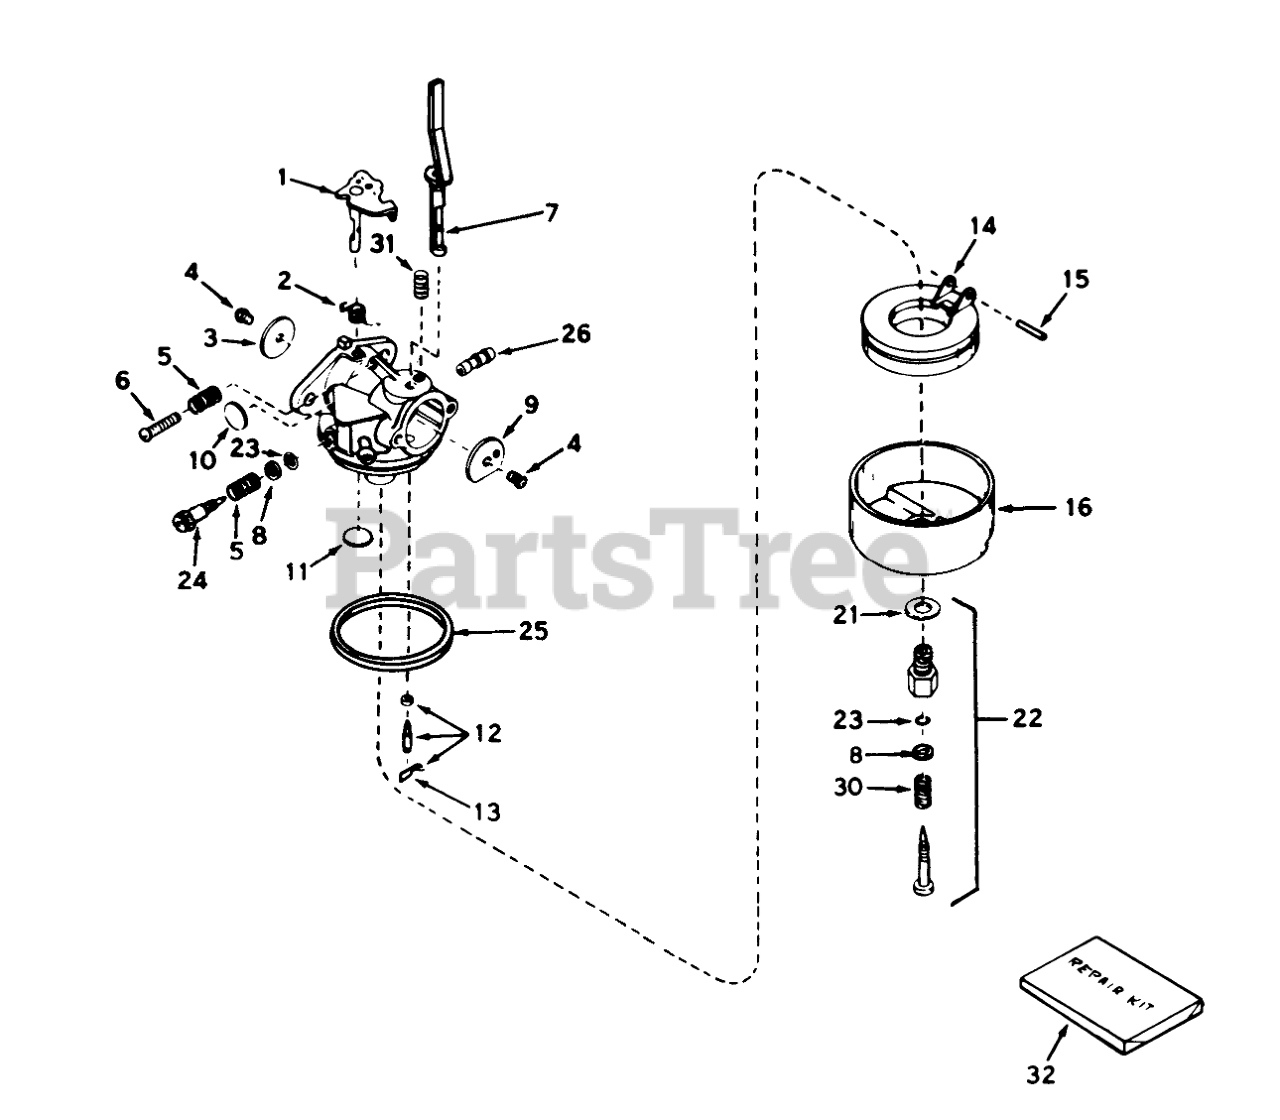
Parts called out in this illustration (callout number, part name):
1	Shaft/Lever-Throttle
2	Spring, Return
3	Shutter-Throttle
4	Screw-Shutter
5	Spring-Tension
6	Screw-Throttle Crack Screw / Idle Speed
7	Shaft & Lever Assy., Choke
9	Shutter-choke
10	Plug-Welch, Idle Mixture Well
11	Plug-Welch, Atmospheric Vent
12	Inlet Needle, Seat & Clip Assy. (Incl. Ref. #13)
13	Clip-Spring
14	Float
15	Shaft-Float
16	Bowl-Float (no drain)
21	Washer-Bowl Nut
22	Adjustment Screw Assy., Main (Incl. Ref. #8, 21, 23 & 30)
23	"O"Ring
24	Screw, Idle Adj.
25	O Ring-Bowl, Float
26	Fuel Fitting
31	Spring-Positioning, Choke
32	Kit-Repair
